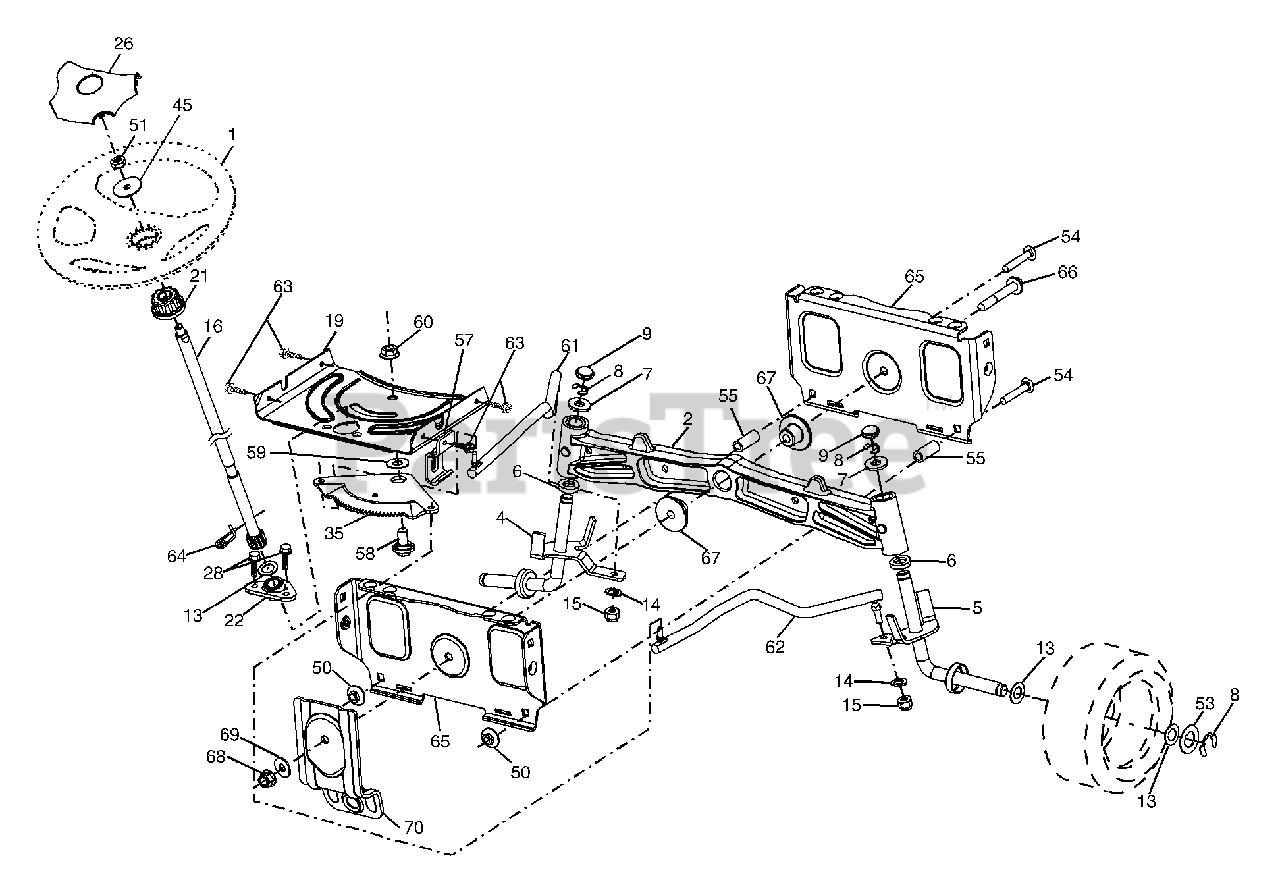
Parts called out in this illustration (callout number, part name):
1	Wheel, Steering
2	Axle Asm., Front
4	Spindle Asm., LH
5	Spindle Asm., RH
6	Bearing, Race Thrust Harden
7	Washer 25/32 x 1-5/8 x 16 Ga.
8	Ring, Klip #T5304-75
9	Cap, Spindle
13	Washer 25/32 x 1-1/4 x 16 Ga.
14	Washer, Lock Hvy Hlcl Spr 3/8
15	Nut, Crown Lock 3/8-24 unf
16	Shaft Steering
19	Plate Steering
21	Adapter, Wheel Steering
22	Bushing, Strg. Blk
26	Insert, Wheel Steering
28	Screw 3/8-16 x 3/4
35	Gear, Sector Plate
45	Washer 9/16 ID x 2-3/8 OD x 12 Ga.
50	Nut Lock 3/8-16 unc
51	Nut Hex Jam Toplock 1/2-20 unf
53	Washer Hardened .793 x 1.637 x .060
54	Bolt Hex 3/8-16 unc x 2-1/4
55	Spacer Brace Axle
57	Bracket Upstop
58	Bolt Shoulder Sector Pivot CFM
59	Washer Thrust Sector Steering
60	Nut Flange Lock 5/8-11
61	Draglink LH
62	Draglink, RH
63	Screw 5/16-18 x 3/4
64	Retainer Clip Spring Steering
65	Brace Axle Front
66	Bolt Hex Fghd 7/16-14 x 3 Serr
67	Bushing PM Front Axle
68	Nut Lock Flange 7/16-14 Gr. 5
69	Washer 1.5 x .505 x .118
70	Bracket Deck Susp. Front
